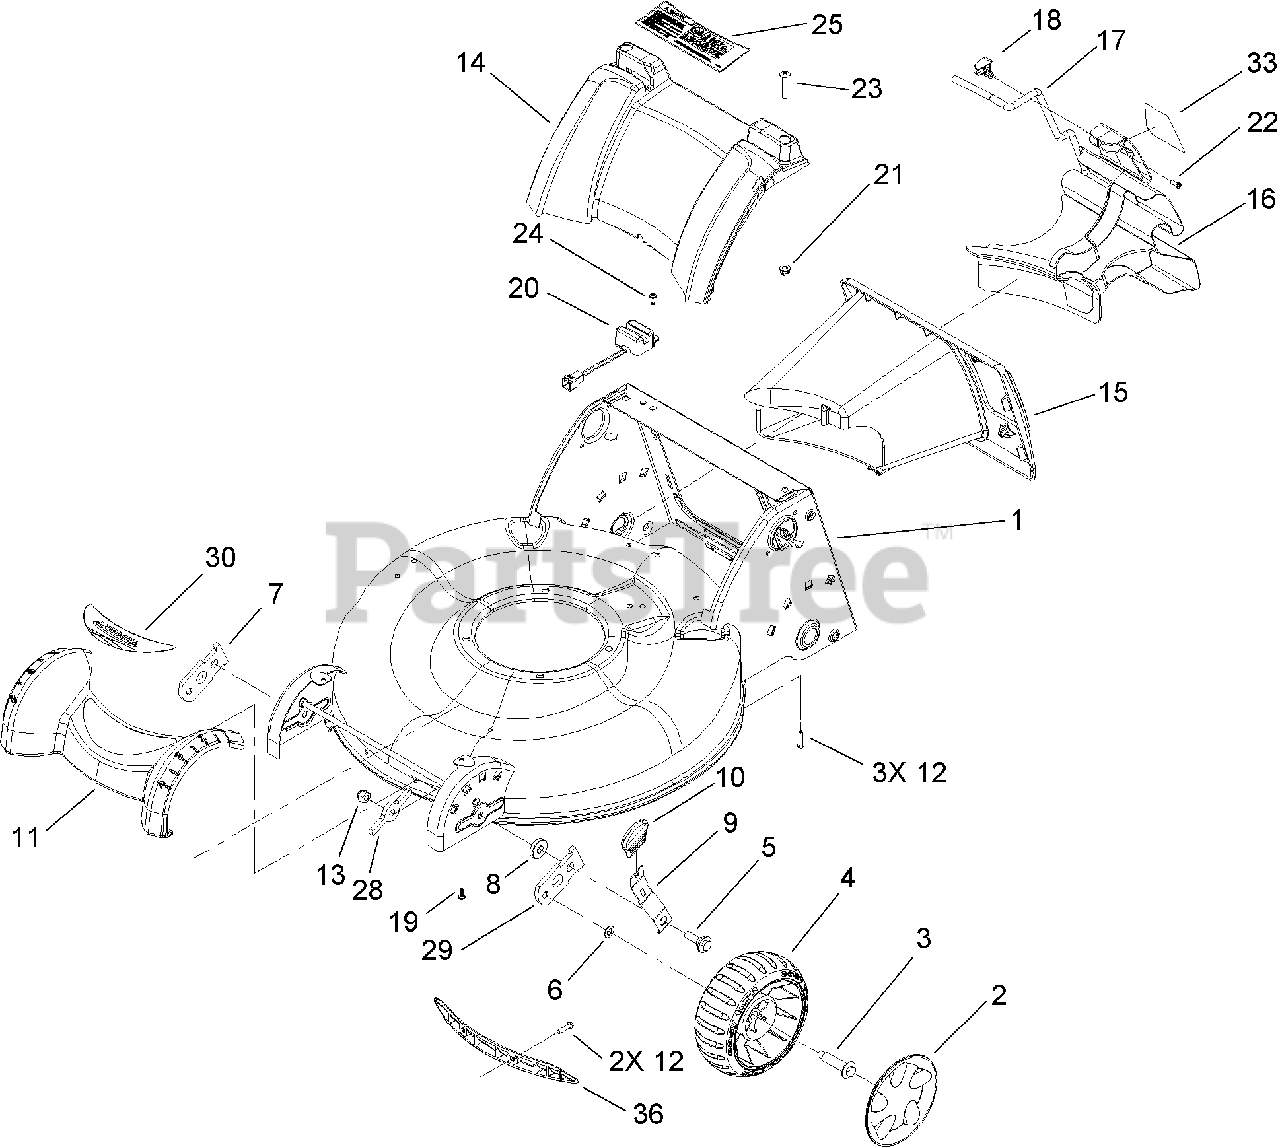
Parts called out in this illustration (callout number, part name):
1	HOUSING ASM
2	COVER-WHEEL, 7IN
3	BOLT-SHOULDER
4	7IN WHEEL ASM
5	BOLT-SHOULDER
7	ARM-PIVOT, RH
9	ARM-SPRING
10	KNOB-LEVER, HOC
11	COVER-FRONT
12	SCREW-PLASTITE
13	NUT-LOCK, NI
14	COVER-REAR
15	TUNNEL
16	PLUG-CHUTE
17	LATCH-PLUG
18	RETAINER-LATCH
19	SCREW-PLASTITE
20	MODULE-SWITCH
21	NUT-CLIP
22	SCREW-PPH
23	SCREW-PTH
24	SCREW-THREAD FORMING
25	DECAL-DANGER
28	WASHER-SUPPORT, FRONT
29	ARM-PIVOT, LH
36	INSERT-HOUSING
